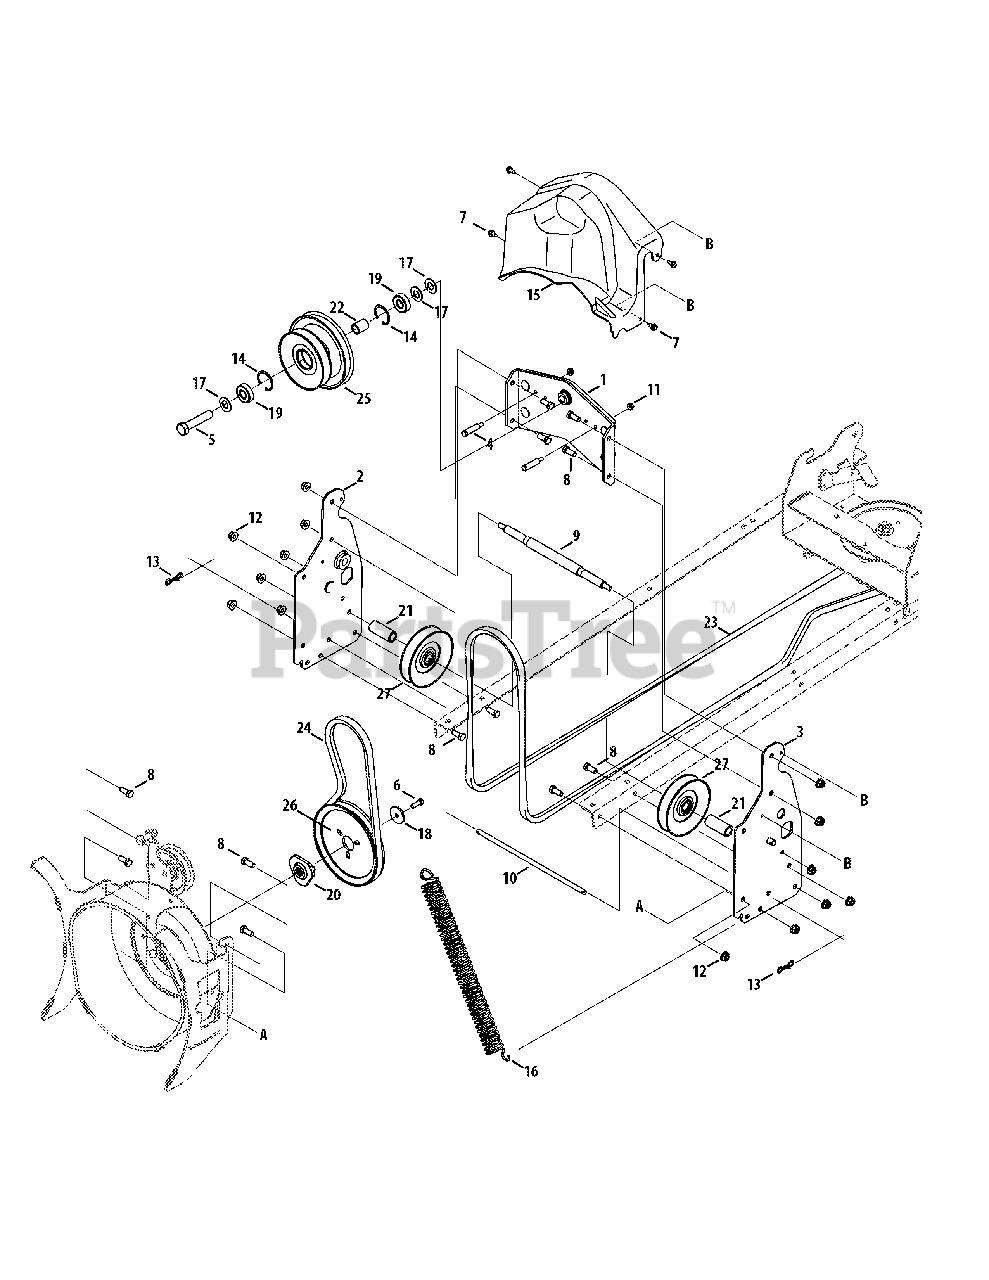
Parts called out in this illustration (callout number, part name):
1	Bracket Assembly, Supt, Spndl
2	Bracket Assembly, Frm, RH
3	Bracket Assembly, Frm, LH
4	Bolt, Shoulder, Hex Hd
5	Hex Screw, 5/8-18, 3.00, Gr5, Std
6	Hex Screw, 5/16-24, .875, Gr8, Lock
7	Screw, Self-tapping, 1/4-20 x .625
8	Hex Screw, 3/8-16, .880, Gr5, Std
9	Shaft, Supt, Mule Idler
10	Shaft, .375Od x 12.3450 Lg
11	Nut, Flange Lock, 1/4-20, Grf, Nylon
12	Nut, Flange Lock, 3/8-16, Grf, Nylon
13	Pin, Cotter, Bow-Tie 91
14	Ring, Ret, Int
15	Cover, Belt
16	Spring, Extension, 1.6 OD x 7.584 Lg
17	Washer, Flat, .65 x 1.25 x .075
18	Washer, Flat, .34 x 1.50 x .150
19	Bearing, Ball, .625 x 40 x 12
20	Pulley, Adapter, .75 Dia w/ Pins
21	Spacer, .65 ID x .96 OD x 2.31
22	Spacer, .88 OD x .635 ID x 1.105
23	Belt, V-type, Bsec, 138.4
24	Belt, V-type, Bsec x 39.988
25	Pulley, Double, 6.663/5.205 Dia
26	Pulley, V-Type, 7.25 Dia
27	Pulley, Idler, 5.06 Dia
